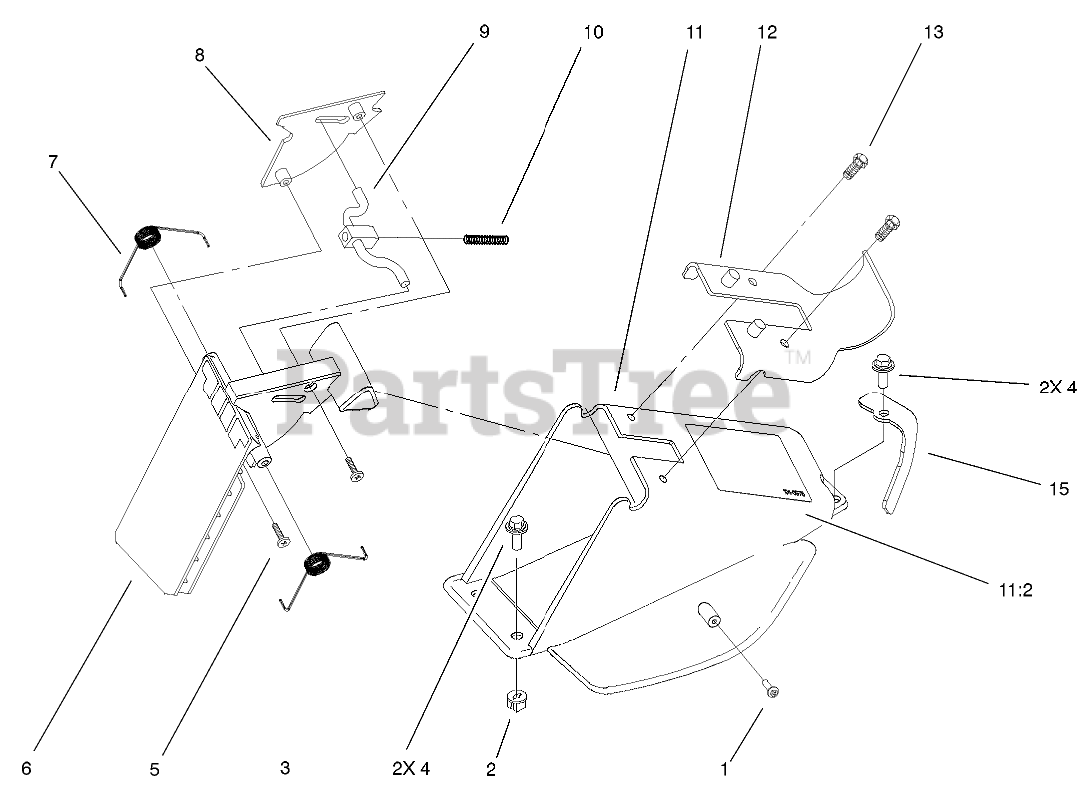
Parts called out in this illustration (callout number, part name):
1	SCREW-PPH
2	NUT - CLIP
4	SCREW-HWH
6	DOOR-DISCHARGE
7	SPRING-DOOR, RH
8	DOOR COVER
9	LATCH-DOOR
10	SPRING-COMPRESSION, LATCH
11	DISCHARGE CHUTE ASM
11:2	DECAL-DANGER
12	PLATE-CHUTE, DISCHARGE
13	SCREW-PLASTITE
15	CLAMP-DOOR
16	DECAL-DANGER
